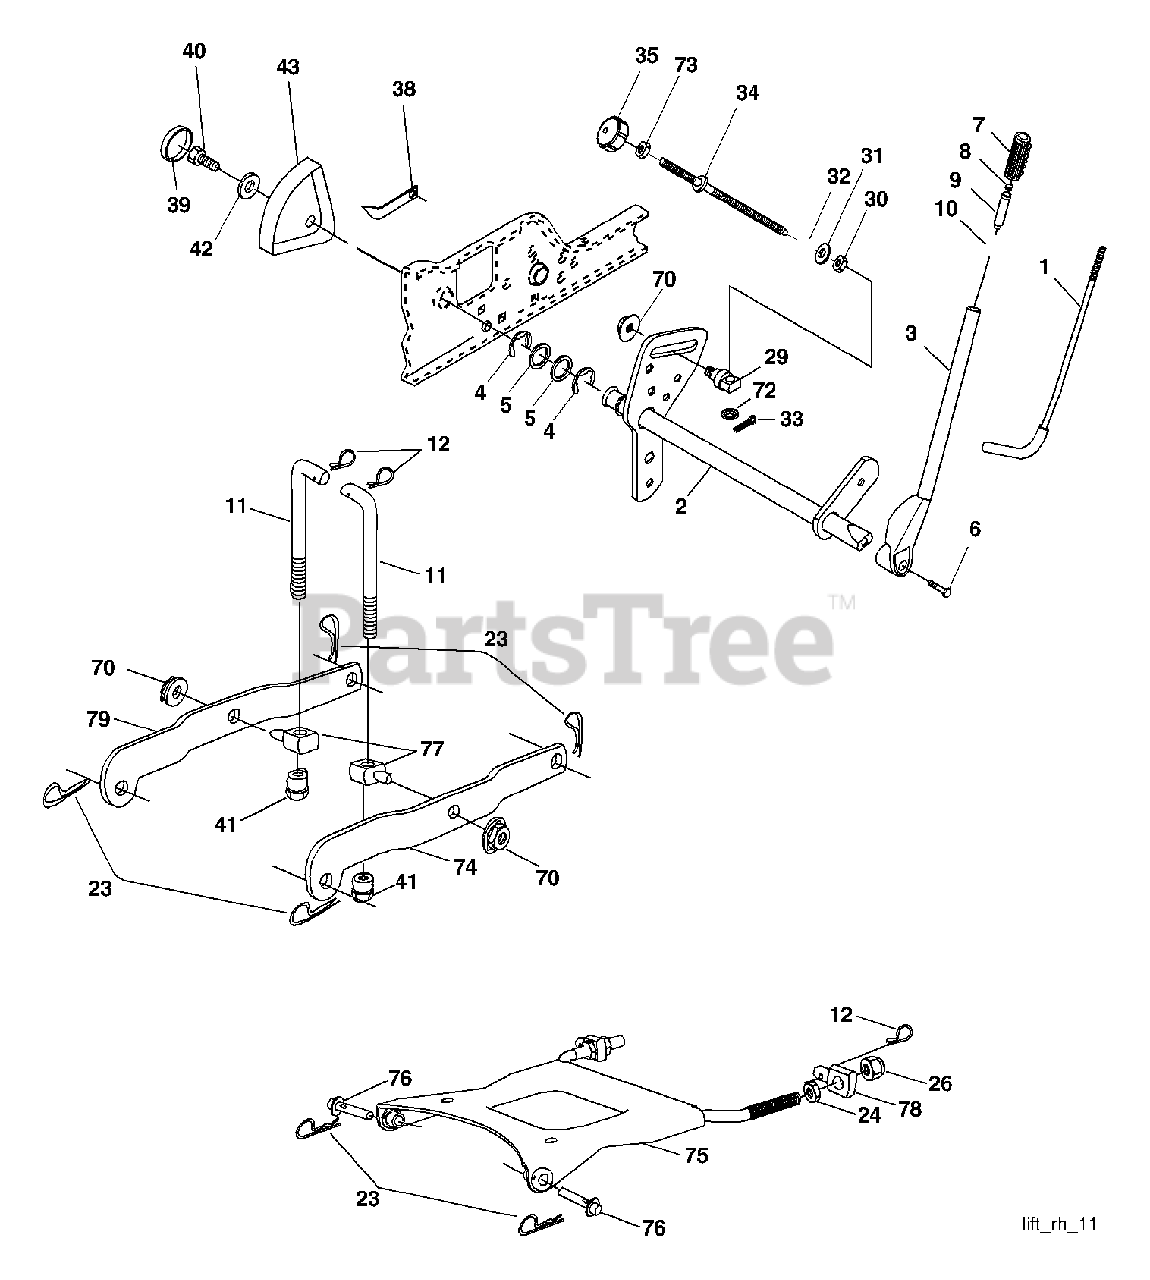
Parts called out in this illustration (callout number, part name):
1	Rod Asm., Lever
2	Shaft Asm., Lift Vgt
3	Lever Asm., Lift Rh
4	E-Ring Truarc #5133-87
5	Washer 29/32 x 1-1/4 x 16 Ga.
6	Bolt, Fin Hex 3/8-16 x 1-1/2
7	Grip, Handle
8	Button, Plunger
9	Plunger, Lever Lift
10	Spring 0.62 OD x 2.125
11	Link Lift
12	Retainer, Spring
23	Retainer, Spring
24	Nut, Jam Hex 1/2-13 unc
26	Nut, Lock W/Wsh 1/2-13 unc
29	Trunnion Infin Height
30	Nut, Special
31	Washer 13/32 x 5/8 x 16 Ga.
32	Spring, Compression lnf Hgt
33	Pin, Cotter 3/32 x 1/2
34	Rod, Adj Lift
35	Knob, lnf 3/8-16 unc
38	Pointer Height Indicator
39	Plug, Hole Blk. 1.48511.515 Dia.
40	Screw 5/16-18 x 1
41	Nut, Crownlock 318-24
42	Washer 11/32 x 1-1/2 x 10 Ga.
43	Scale, Indicator Height
70	Nut Hex Flange Lock
72	Nut Push Phos & Oil
73	Nut, Hex Jam 3/8-16 unc
74	Arm Suspension Rear RH
75	Plate, Asm, Susp, Front
76	Pin Flange
78	Trunnion, Front, Susp
79	Arm, Suspension Rear LH
